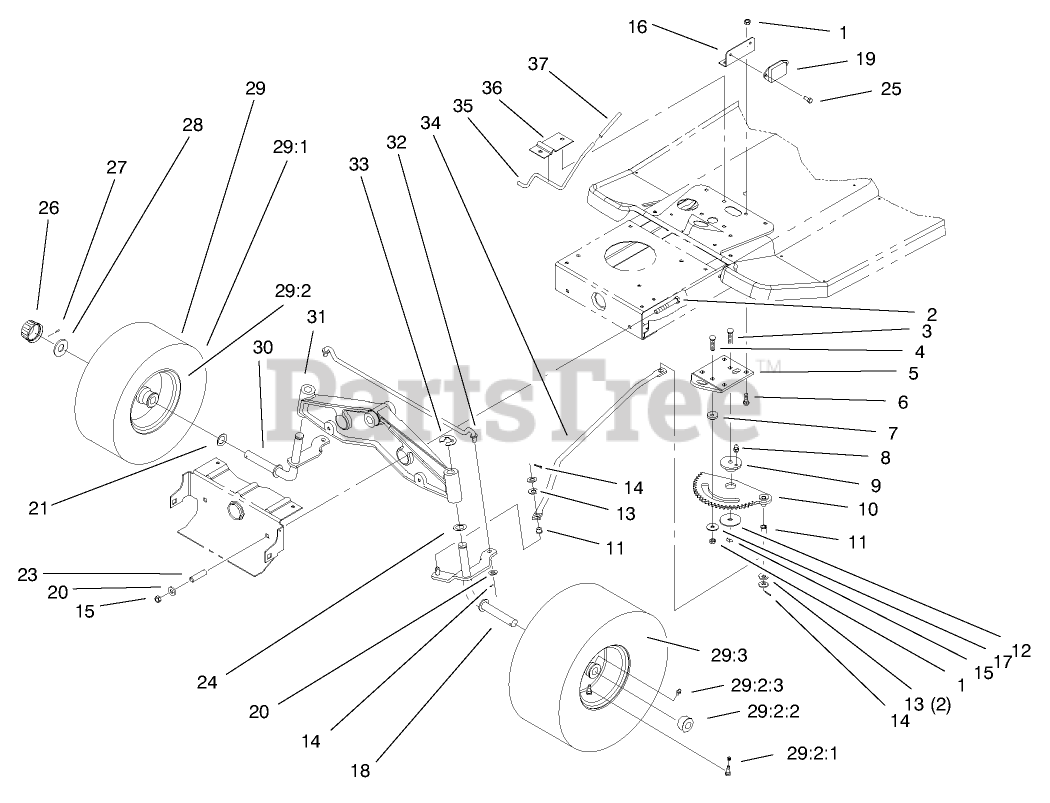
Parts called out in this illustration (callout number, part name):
1	NUT-LOCK, NI
2	SCREW-HH
3	SCREW-CARR
4	SCREW-CARR
5	BRACKET-RACK, STEERING
6	BOLT-CARR
7	SPACER-RACK, STEERING
8	FITTING-GREASE
9	BUSHING-ECCENTRIC
10	RACK-STEERING
11	BUSHING-FLANGED, NYLON
12	WASHER-BEARING
13	WASHER-FLAT
14	PIN-COTTER
15	NUT-LOCK, NI
16	BRACKET-MODULE
17	WASHER-PIVOT
18	LH SPINDLE ASM
19	MODULE
20	WASHER-FLAT
21	WASHER-THRUST
23	SPACER
24	WASHER-THRUST
25	SCREW-HWH
26	CAP-HUB
27	PIN-COTTER
28	WASHER-PLAIN
29:2:2	BEARING-WHEEL
29:2:3	FITTING-GREASE
30	RH SPINDLE ASM
31	AXLE-FRONT
32	TIE ROD-STEERING
33	E-RING
34	LINK-DRAG
35	ROD-BRAKE, PARKING
36	BRACKET-PARKING BRAKE
37	GRIP-BRAKE, PARKING
